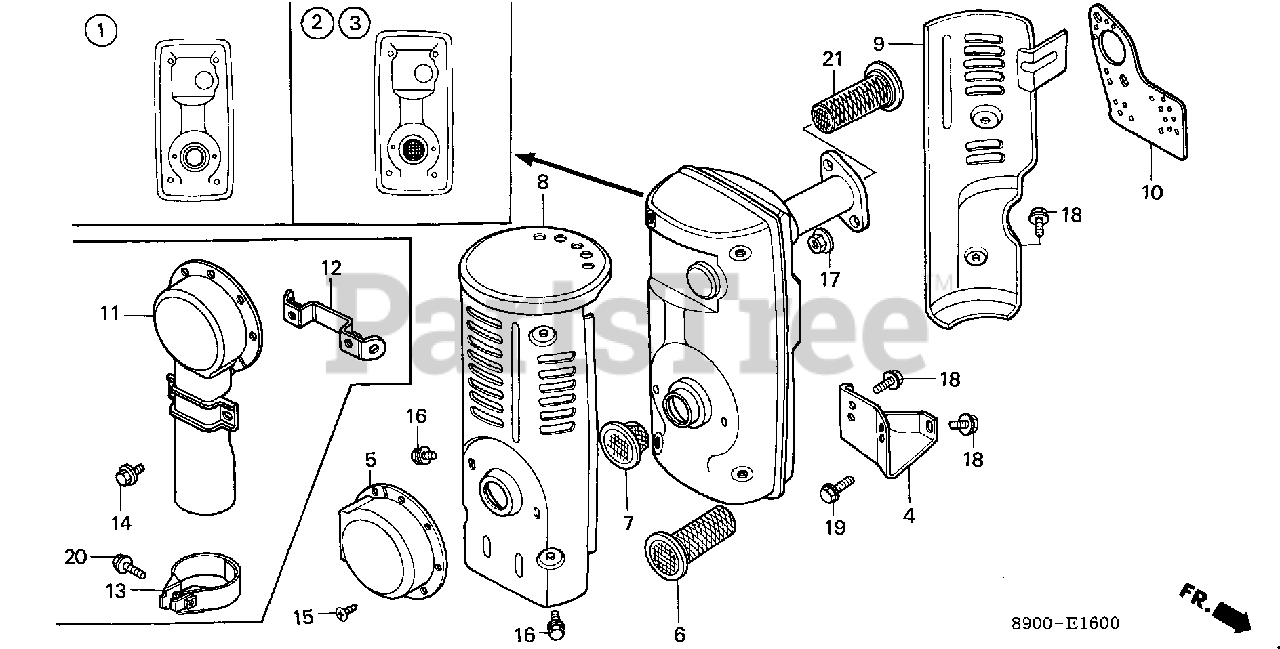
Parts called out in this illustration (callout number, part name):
1	MUFFLER
4	STAY, MUFFLER
5	DEFLECTOR, MUFFLER
6	ARRESTER, SPARK
7	FLANGE, BAFFLE
8	PROTECTOR A, MUFFLER (NOT AVAILABLE)
9	PROTECTOR B, MUFFLER
10	GASKET, MUFFLER
11	PIPE, MUFFLER TAIL
12	HOLDER, TAIL PIPE
13	BAND, TAIL PIPE
14	BOLT, FLANGE (6X8)
15	SCREW, TAPPING (4X8)
15	SCREW, TAPPING (4X6)
16	BOLT-WASHER (6X10) (NOT AVAILABLE)
17	NUT, FLANGE (8MM)
18	BOLT, FLANGE (6X10)
19	BOLT, FLANGE (8X16)
20	BOLT, FLANGE (8X16)
